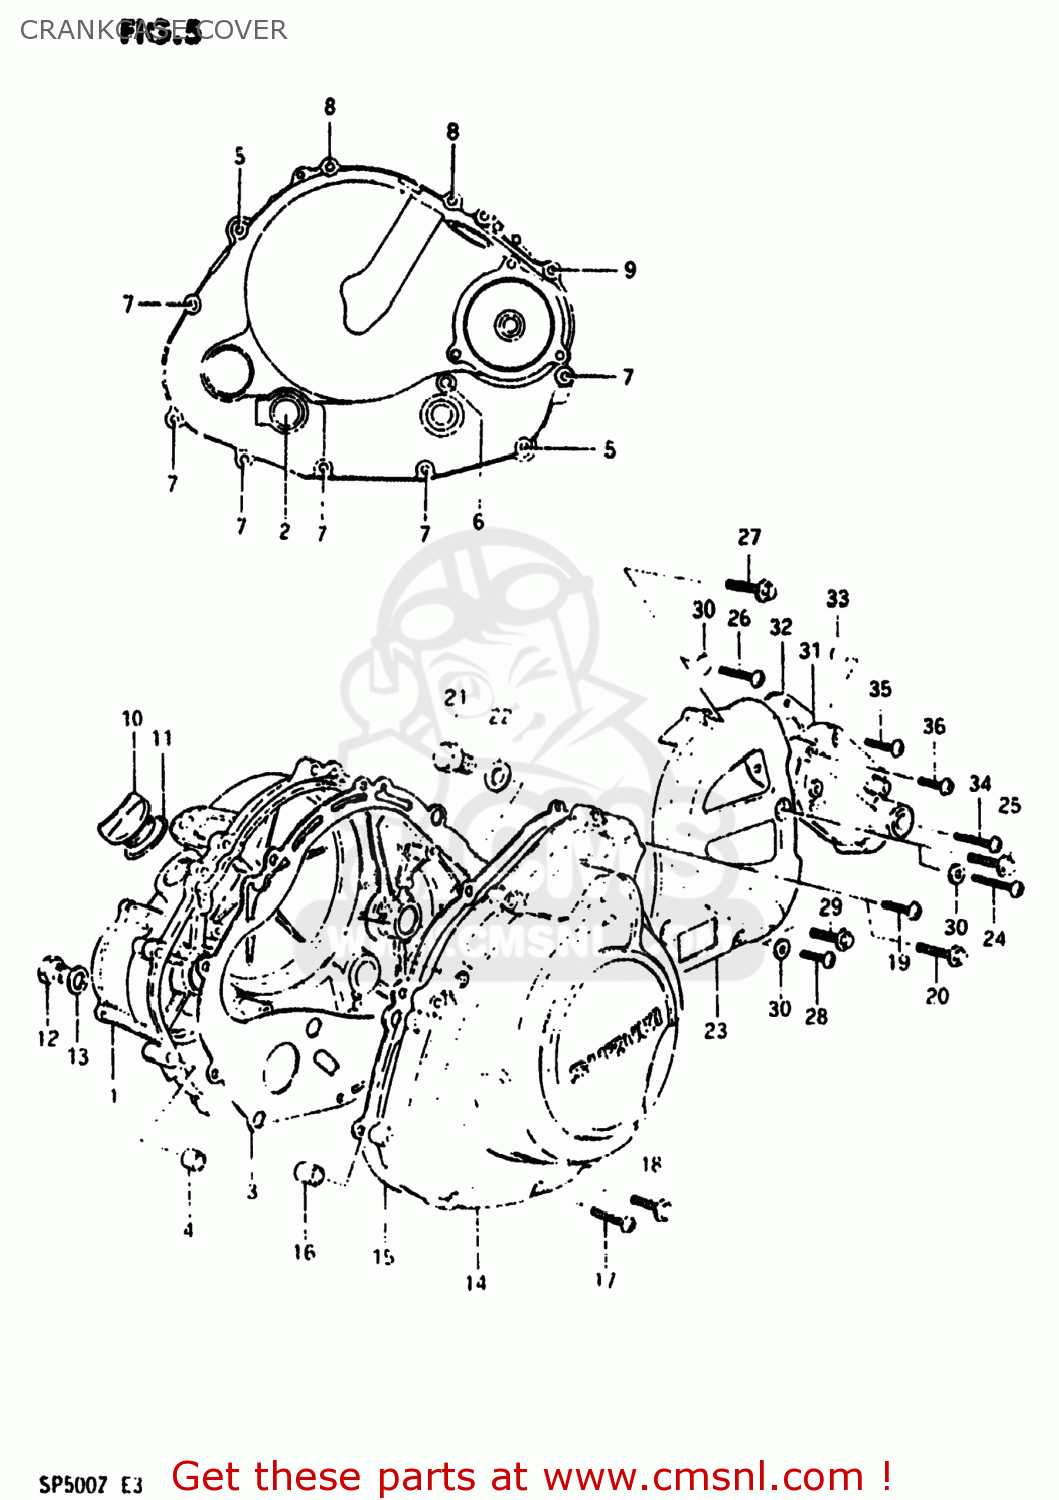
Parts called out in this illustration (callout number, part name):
1	COVER,CLUTCH
2	LENS,OIL LEVEL CHECK
3	GASKET,CLUTCH COVER (MCA)
4	PIN
5	SCREW
6	SCREW
7	BOLT (6X35)
8	BOLT
9	SCREW(6X25)
10	CAP
11	O RING(D:2.2,ID:32)
12	PLUG (14X12)
13	GASKET(14X19.2X2) (NAS)
14	COVER
15	GASKET,MAGNETO COVER (MCA)
16	PIN
17	SCREW 6X30
18	BOLT (6X30)
19	SCREW
20	BOLT
21	PLUG(12X9)
22	GASKET(12X16X2) (NAS)
23	COVER,ENGINE SPROCKET
24	SCREW (6X45)
25	BOLT
26	SCREW 6X30
27	BOLT (6X30)
28	SCREW
29	BOLT (6X20)
30	WASHER
31	COVER,GEAR SHIFT
32	CUSHION,ENGINE SPROCKET
33	PIN
34	SCREW (6X35)
35	SCREW 6X30
36	SCREW
